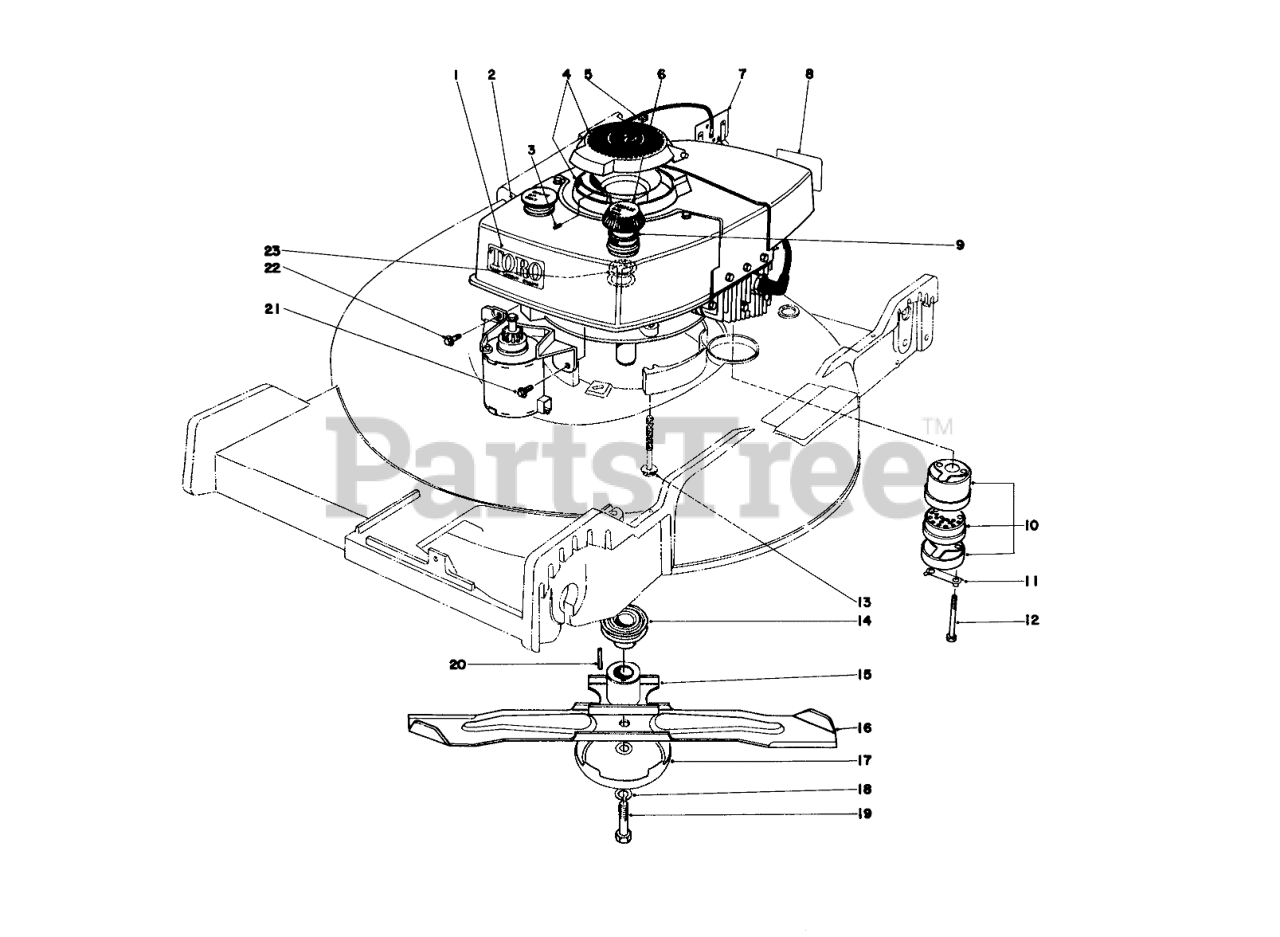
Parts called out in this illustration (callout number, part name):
1	High Torque
2	Engine
3	SPRING PIN
4	Cover
5	WIRE CLIP
6	Gas Cap Assembly (Incl. Ref. #9 & 23)
7	SWITCH & TERM BLK CVR
8	Decal Maintenance
9	GASKET
10	Muffler Assembly (Incl. Ref. #11 & 12)
11	CLIP - LOCKING
12	SCREW-HH
13	3/8-16 X 2-3/4 CAPSCR
14	DRIVER PULLEY
15	Blade Retainer
16	Blade
17	AntiScalp Cup
18	WASHER-LOCK
19	SCREW-BLADE
20	Key Square
21	SCREW
22	Screw
23	GAS CAP BAFFLE
